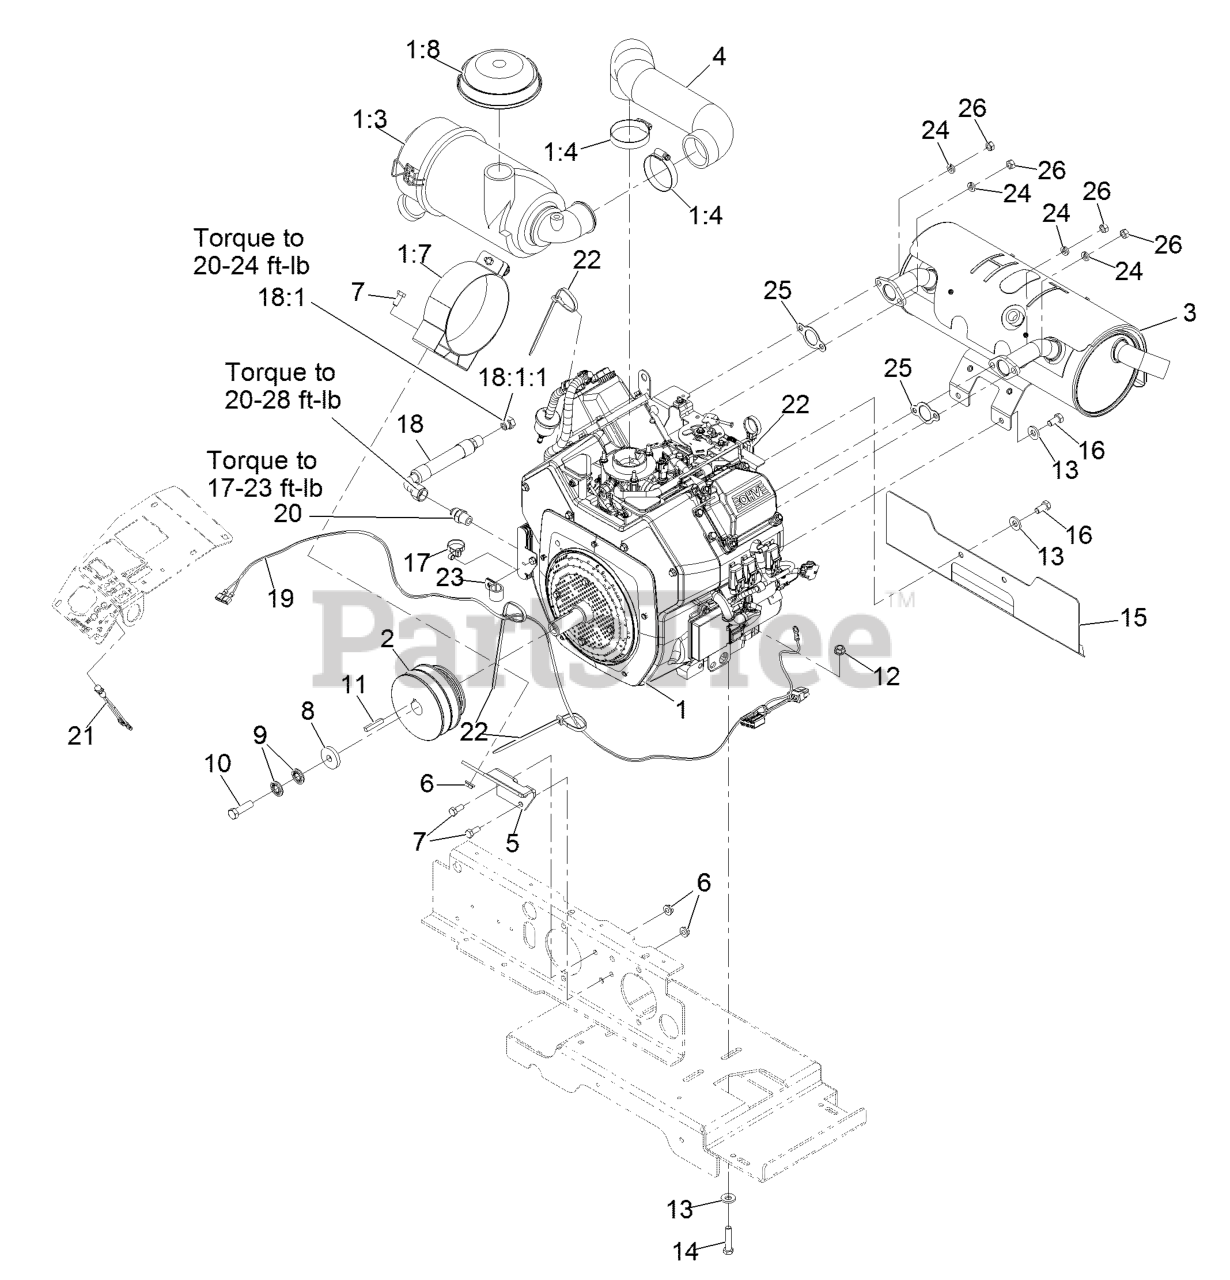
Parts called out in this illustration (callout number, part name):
1	Asm-Engine 730kc Efi
1:3	AIR CLEANER CANISTER ASM
1:4	CLAMP-HOSE
1:7	BRACKET-FILTER, AIR
1:8	HOOD-CLEANER, 2" AIR INTA
3	MUFFLER
4	HOSE-EFI AIR INTAKE
5	BRACKET-FILTER, AIR
7	SCREW-HH
8	WASHER-CLUTCH
9	WASHER-SPRING
10	SCREW-HH
11	KEY-SQUARE
12	NUT-HHF, WHIZ
13	WASHER-BELLEVILLE
14	SCREW-HH
15	SHIELD-EXHAUST
16	SCREW-HH
17	Tie-Cable
18	OIL DRAIN HOSE ASM
18:1	PLUG-HH
18:1:1	O-RING
19	HARNESS-LIGHT INDICATOR (
20	FITTING-STRAIGHT
21	INDICATOR-LED, RED
22	TIE-PLASTIC
23	CLIP-LOOM
24	WASHER-LOCK
26	NUT-HEX
